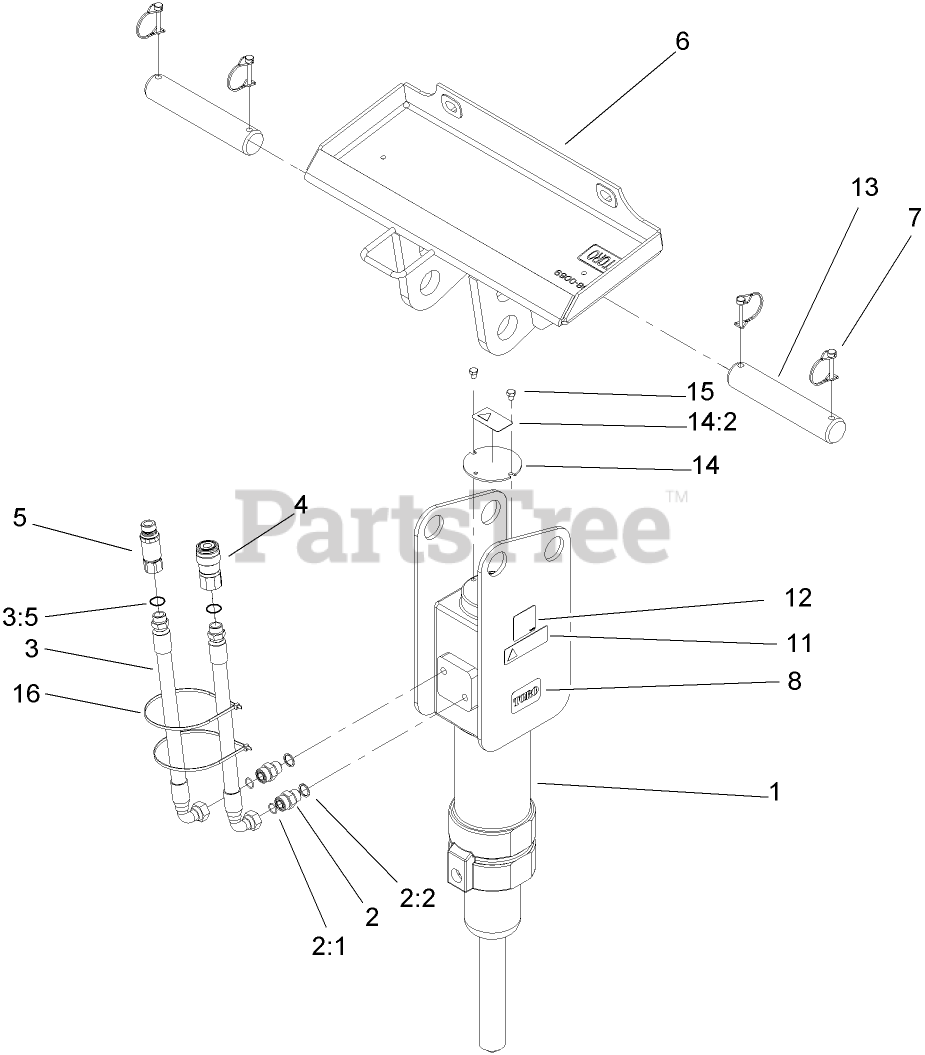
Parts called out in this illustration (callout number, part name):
1	Power Head ASM
2	FITTING-STRAIGHT
2:1	O-RING
2:2	O-RING
3	HOSE-HYDRAULIC
3:4	COVER-TUBING
3:5	O-RING
4	COUPLER-FACE, FLUSH
5	NIPPLE-CONNECT, PRESSURE
6	QUICK ATTACH BREAKER ASM
7	PIN-HITCH
8	DECAL
11	DECAL-WARNING
12	DECAL-GREASE
13	PIN-BREAKER
14	PLATE-COVER
14:2	DECAL-WARNING
15	SCREW-HH
16	TIE-CABLE
